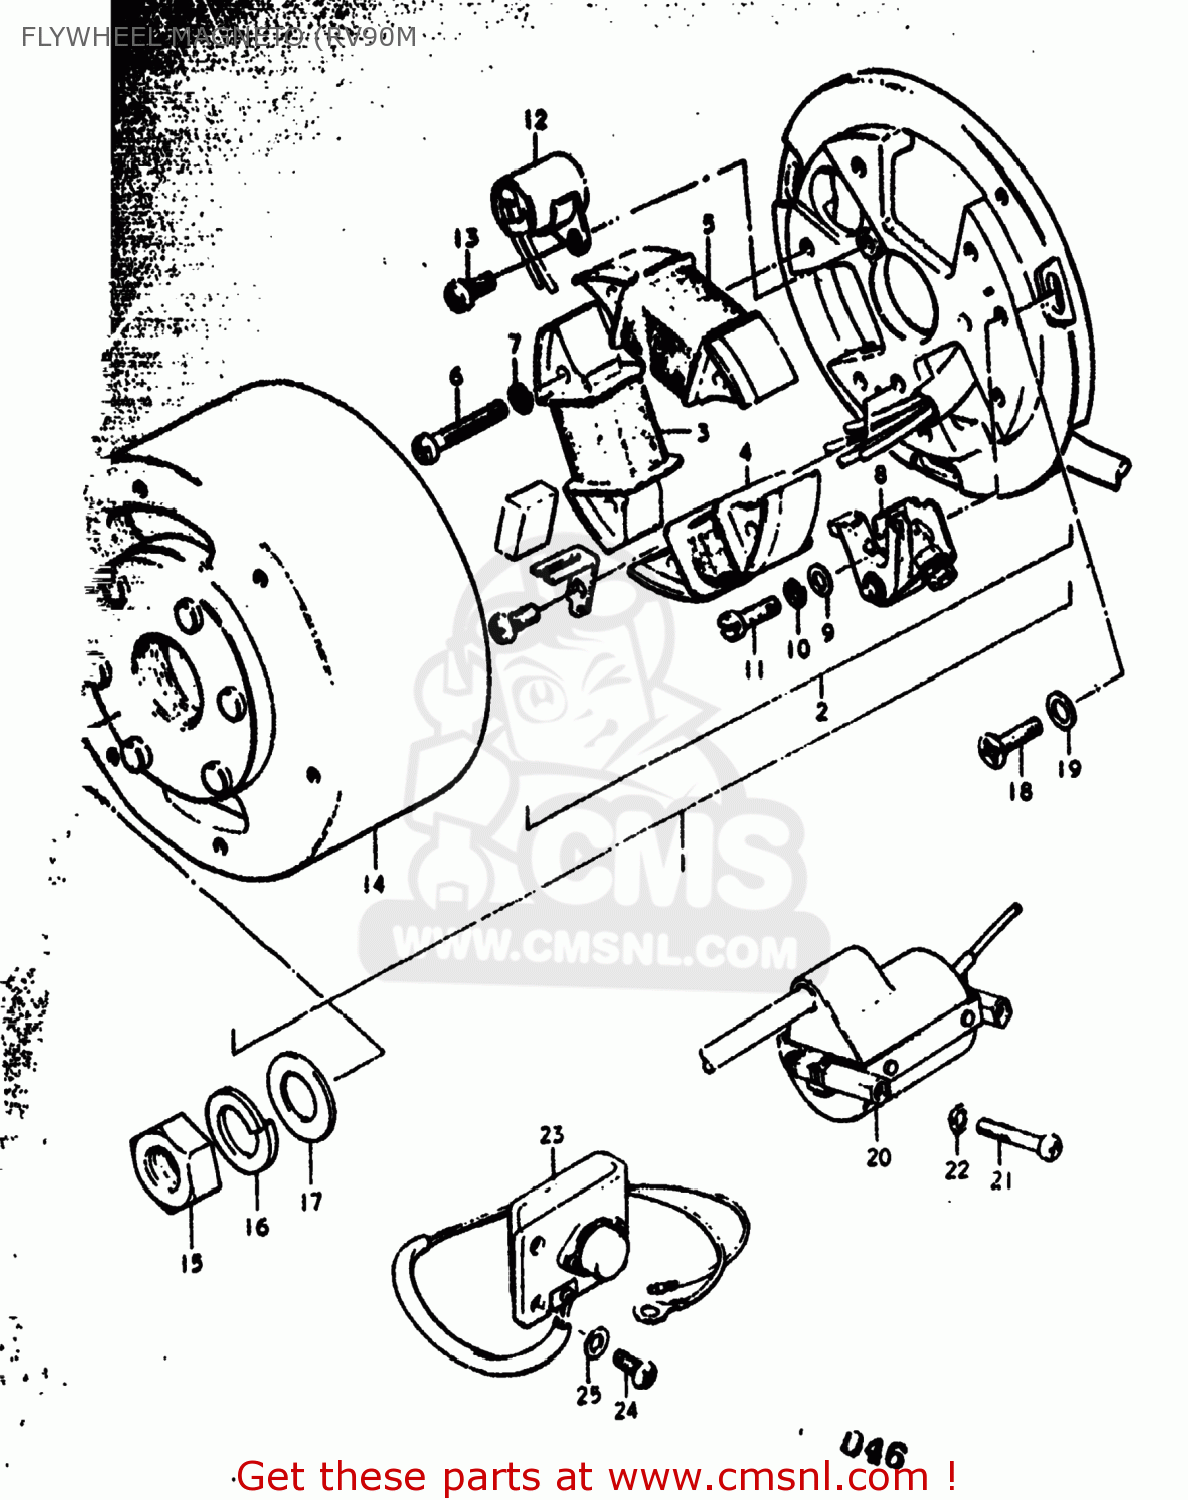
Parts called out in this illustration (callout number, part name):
1	MAGNETO ASSEMBLY
2	STATOR ASSEMBLY
3	COIL,LIGHTING
4	COIL,LIGHTING
5	COIL,PRIMARY
6	SCREW
7	LOCK WASHER
8	POINT ASSEMBLY,CONTACT
9	WASHER
10	LOCK WASHER
11	.SCREW
12	CONDENSER
13	SCREW
14	ROTOR,FLYWHEEL
15	NUT (10MM)
16	LOCK WASHER
17	WASHER
18	SCREW
19	WASHER
20	COIL ASSEMBLY,IGNITION
21	Screw
22	LOCK WASHER
23	REGULATOR, VOLTAGE M,A,B
24	SCREW 6X12
25	WASHER
